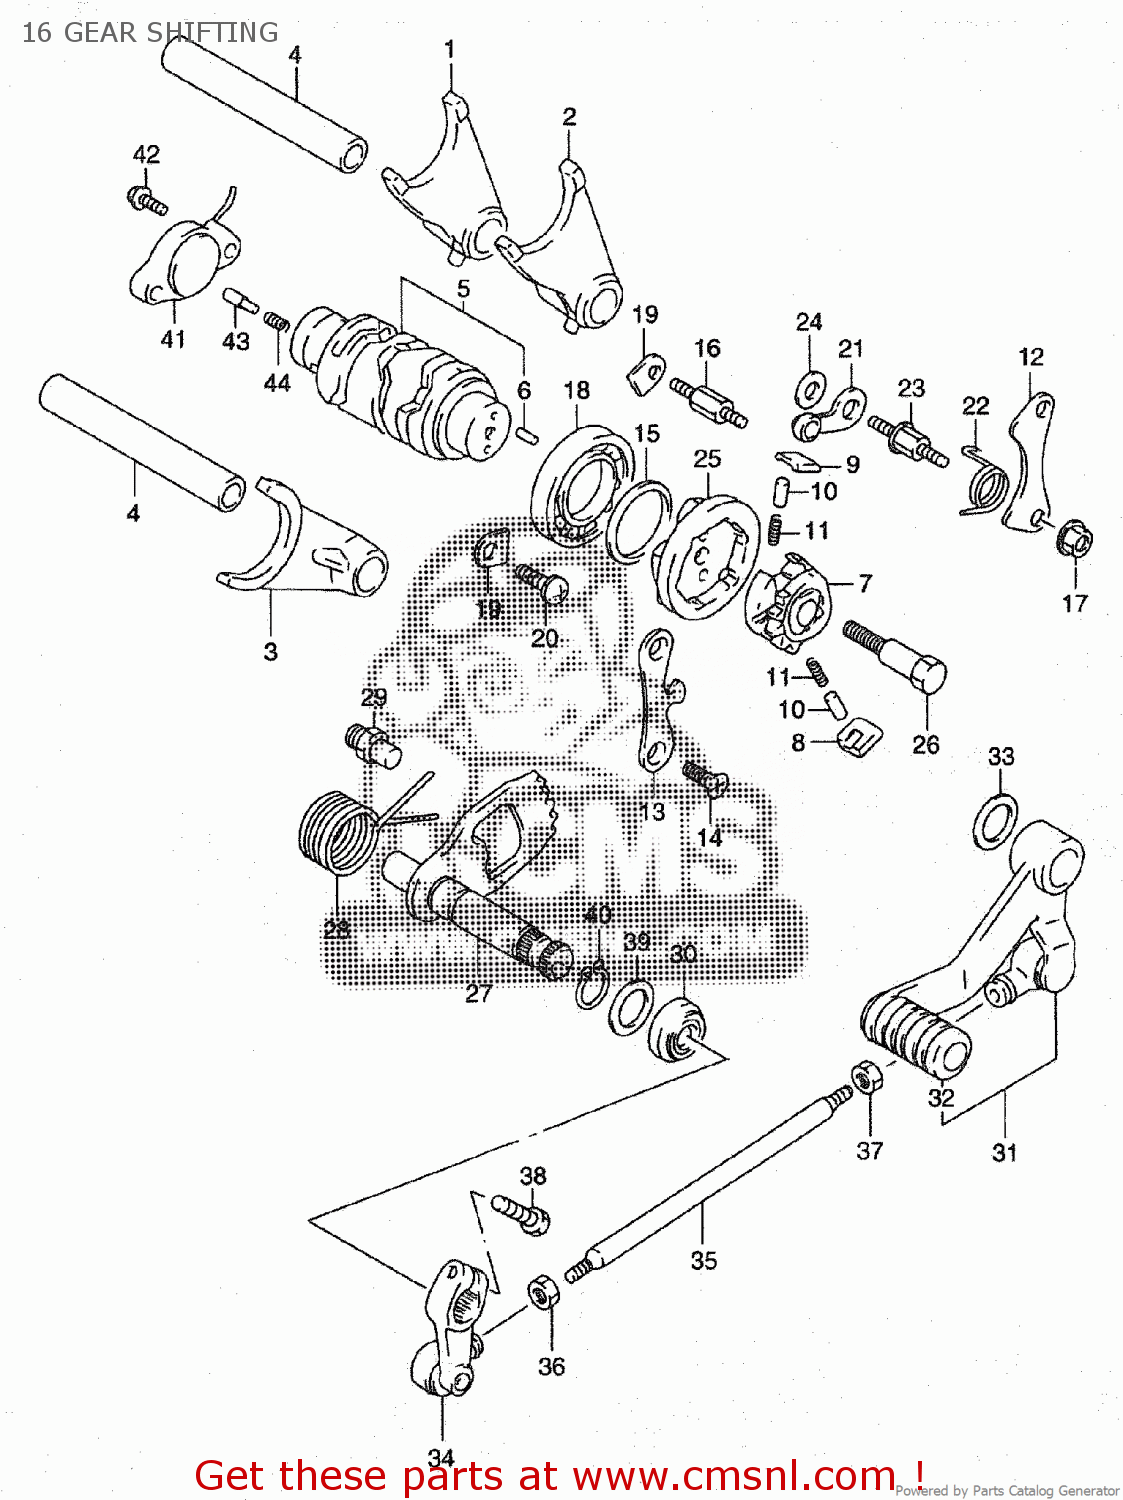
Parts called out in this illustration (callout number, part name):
1	FORK,GEAR SHIFT NO.1
2	FORK,GEAR SHIFT NO.2
3	FORK,GEAR SHIFT NO.3
4	SHAFT,GEAR SHIFT FORK
5	CAM,GEAR SHIFT
6	PIN
7	GEAR,GEAR SHIFT CAM DRIVEN
8	PAWL,GEAR SHIFT NO.1
9	PAWL,GEAR SHIFT NO.2
10	PIN(5X8)
11	SPRING
12	LIFTER,GEAR SHIFT POLE
13	GUIDE,GEAR SHIFT CAM
14	SCREW
15	WASHER(25X32X3)
16	BOSS,SHIFT PAWL LIFTER
17	NUT
18	BEARING(25X47X8)
19	RETAINER
20	SCREW
21	STOPPER,GEAR SHIFT CAM
23	SUPPORT,CAM STOPPER ARM
24	WASHER
26	PIN,SHIFT CAM DRIVEN GEAR
27	SHAFT,GEAR SHIFT
28	SPRING
29	STOPPER,GEAR SHIFT CAM
30	OIL SEAL
32	RUBBER,GEAR SHIFT PEDAL
33	WASHER(18.2X27X1)
34	ARM,GEAR SHIFT LINK
35	ROD GEAR SHIFT LINK
36	NUT
37	NUT
38	BOLT
39	WASHER
40	CIRCLIP,12 MM
41	BASE ASSY,NEUTRAL SW TERMINAL
42	SCREW
43	PIN(5X15.5)
44	SPRING
